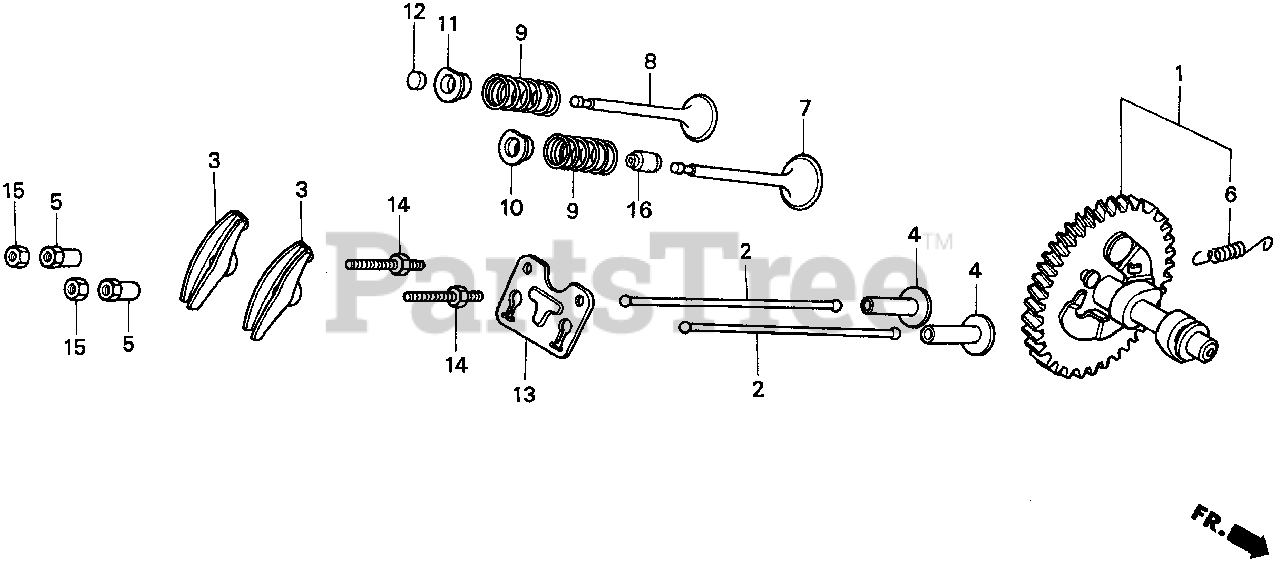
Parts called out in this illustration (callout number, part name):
1	CAMSHAFT ASSY.
2	ROD, PUSH
3	ARM, VALVE ROCKER
4	LIFTER, VALVE
5	PIVOT, ROCKER ARM
6	SPRING, WEIGHT RETURN
7	VALVE, IN.
8	VALVE, EX.
9	SPRING, VALVE
10	RETAINER, IN. VALVE SPRING
11	RETAINER, EX. VALVE SPRING
12	ROTATOR, VALVE
13	PLATE, PUSH ROD GUIDE
14	BOLT, PIVOT (8MM)
15	NUT, PIVOT ADJ.
16	SEAL, VALVE STEM
